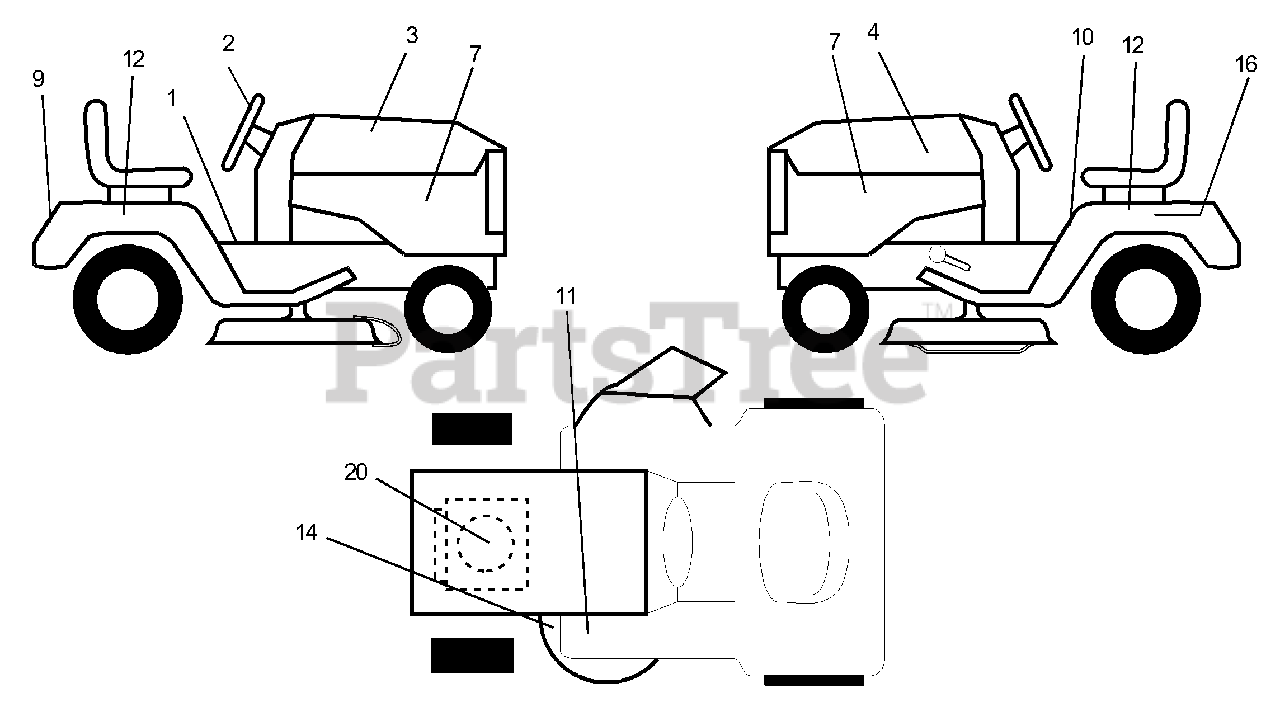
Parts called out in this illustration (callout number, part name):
1	Decal Instruction Operat English
2	Decal Ins Strg Wh
3	Decal Hood Rh
4	Decal Hood Lh
7	Decal Panel Side
9	Decal Fender Logo
10	Decal Danger English
11	Decal Clutch/brake English
12	Decal Fender
14	Decal V-belt Schematic 42"
16	Decal Battery Danger/Poison
20	Decal HP Engine
